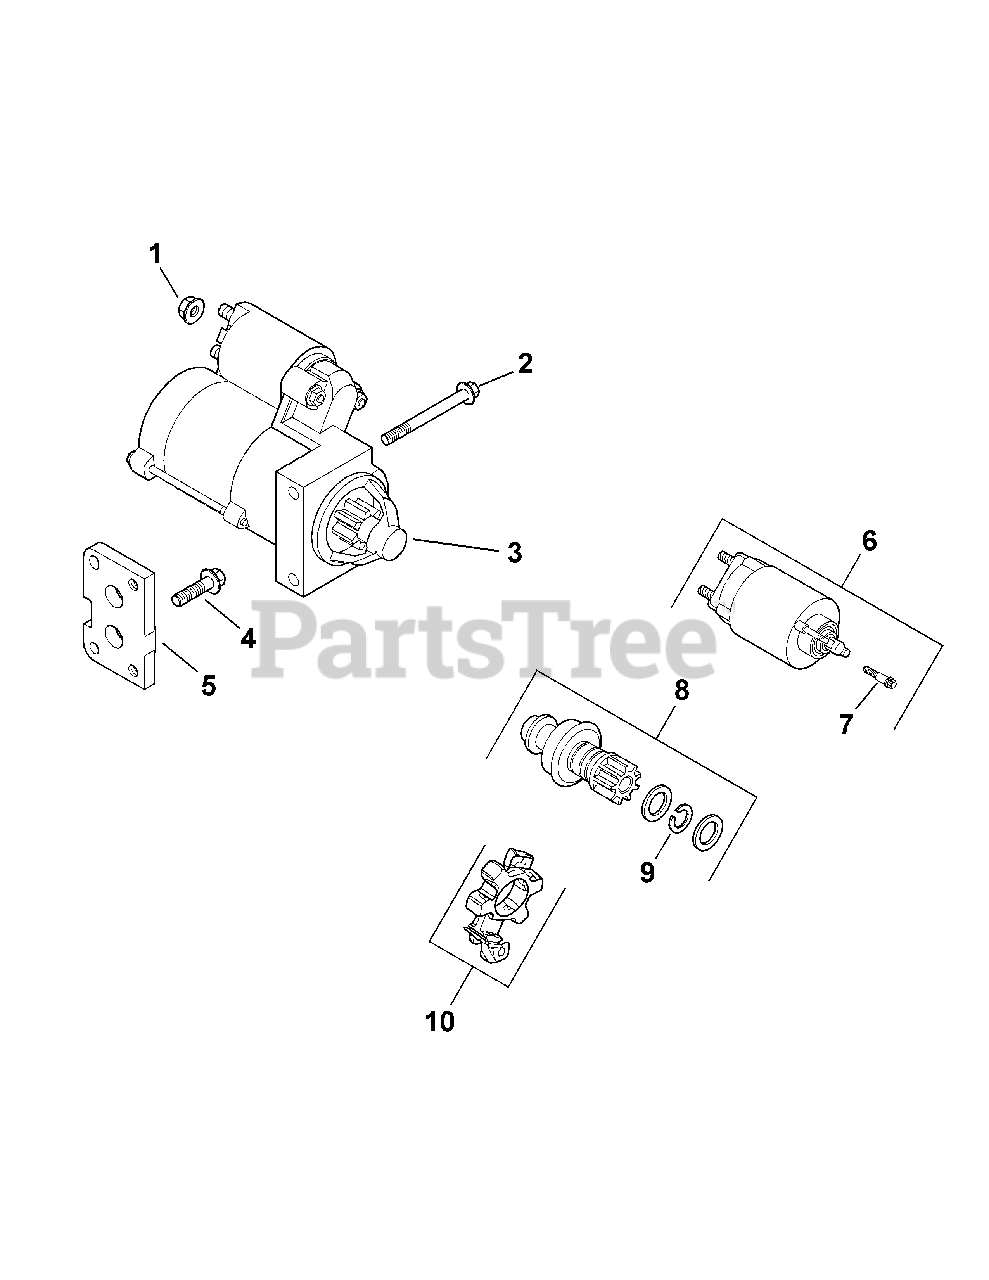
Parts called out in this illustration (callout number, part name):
1	Nut, Flg M8x1.25
3	Starter, Solenoid Shift (Includes 6-10
4	Screw, Flg M8x1.25x30
5	Plate, Starter
6	Kit, Solenoid (Includes 7)
7	Screw, External Torx Head
8	Kit, Starter Pinion (Includes 9)
10	Kit, Brush Holder
